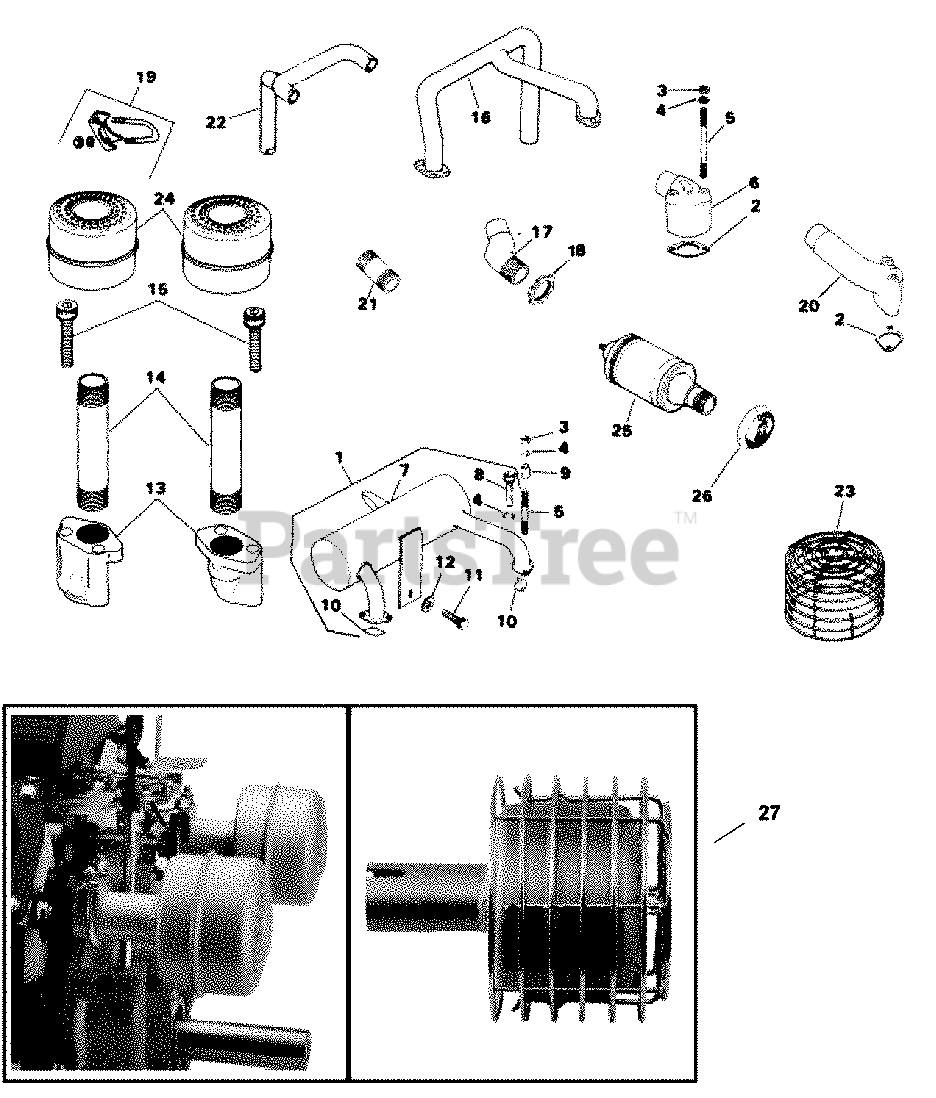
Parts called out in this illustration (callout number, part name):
2	GASKET - USE 52 041 14
4	WASHER, SPRING LOCK 5/16"
5	STUD - DISCONTINUED
13	ADAPTER - DISCONTINUED
20	ELBOW - (#DSC)
27	KIT, MUFFLER W/MOUNTING-DISCONTINUED
